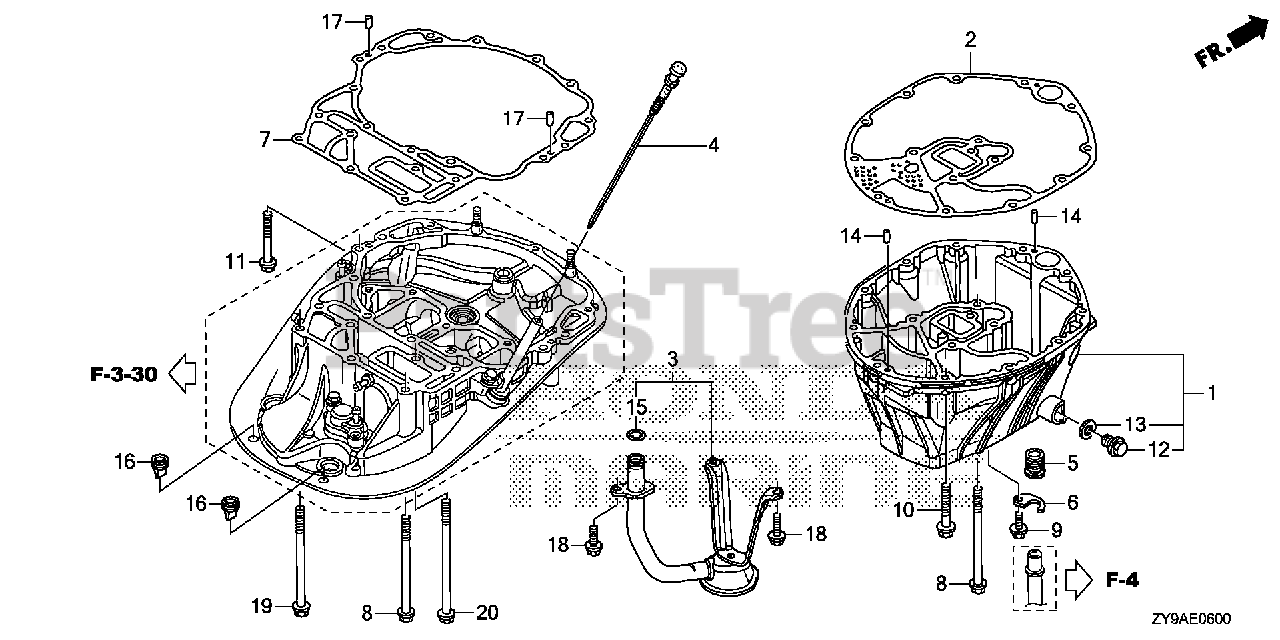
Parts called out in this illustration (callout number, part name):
1	CASE ASSY., OIL *TGRAY* (GRAY)
2	GASKET, OIL PAN
3	STRAINER, OIL
4	DIPSTICK, OIL
5	GROMMET, WATER TUBE
6	PLATE, WATER TUBE
7	GASKET, MOUNT CASE
8	BOLT, FLANGE (8X100)
9	BOLT, FLANGE (6X12)
10	BOLT, FLANGE (8X35)
11	BOLT, FLANGE (8X45)
12	BOLT, DRAIN PLUG
13	WASHER, DRAIN PLUG (12MM)
14	PIN, DOWEL (6X10)
15	O-RING (15.5X2.7)
16	GROMMET (1WAY)
17	PIN, DOWEL (6X10)
18	BOLT, FLANGE (6X16)
19	BOLT, FLANGE (8X100)
20	BOLT, FLANGE (8X120)
